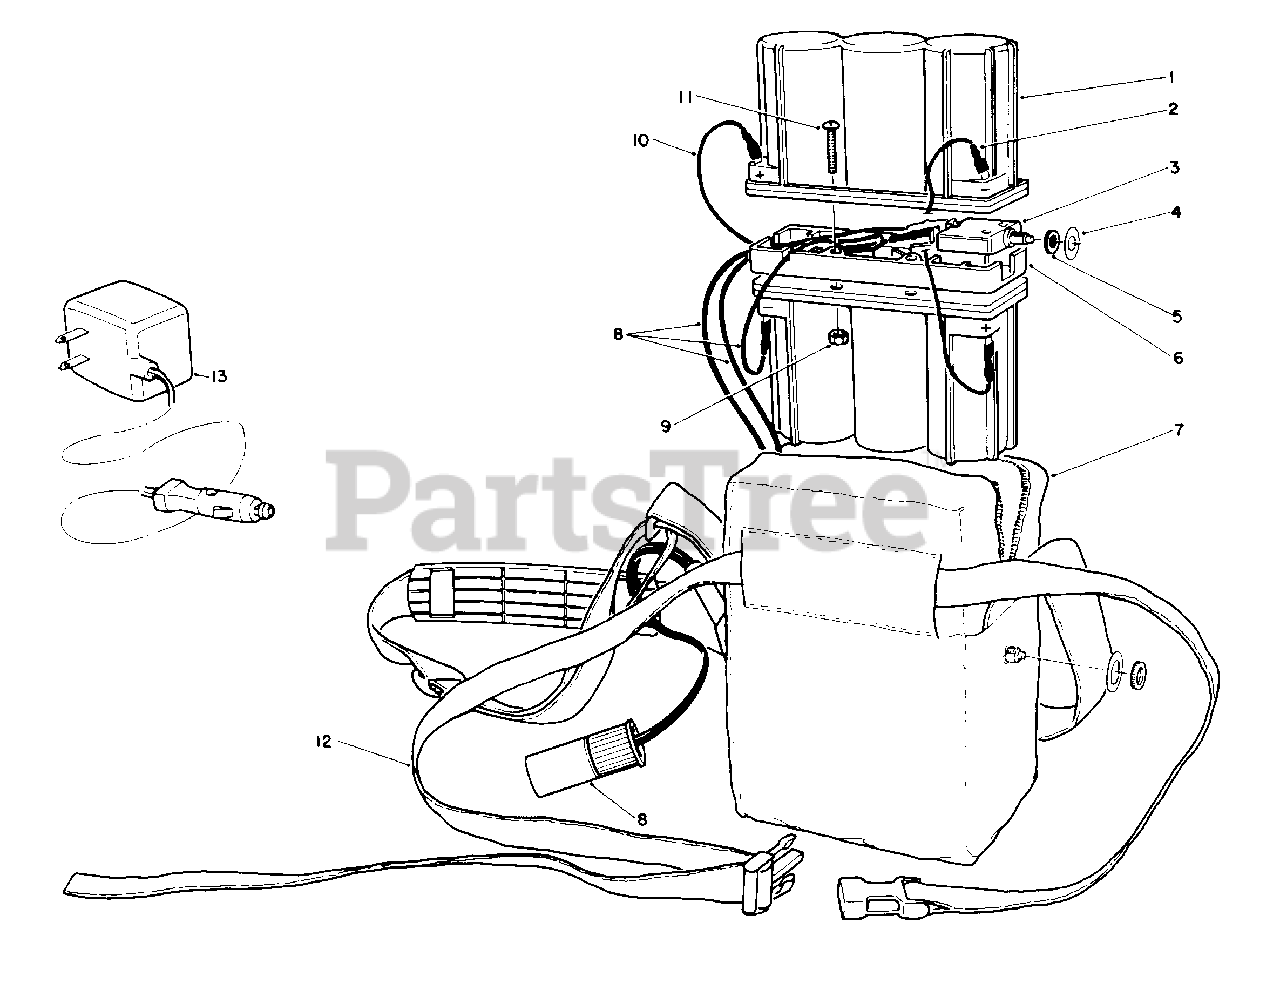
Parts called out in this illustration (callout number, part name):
1	Battery-6 Volt
2	Wire-Battery
3	Circuit Breaker
4	Plate-Breaker, Circuit
5	Nut-Knurled
6	Spacer-Battery
7	Pack-Soft
8	Cord-Battery
10	Wire-Breaker, Circuit
11	Screw-Phillips, Pan Hd.
13	Charger 12 Volt
